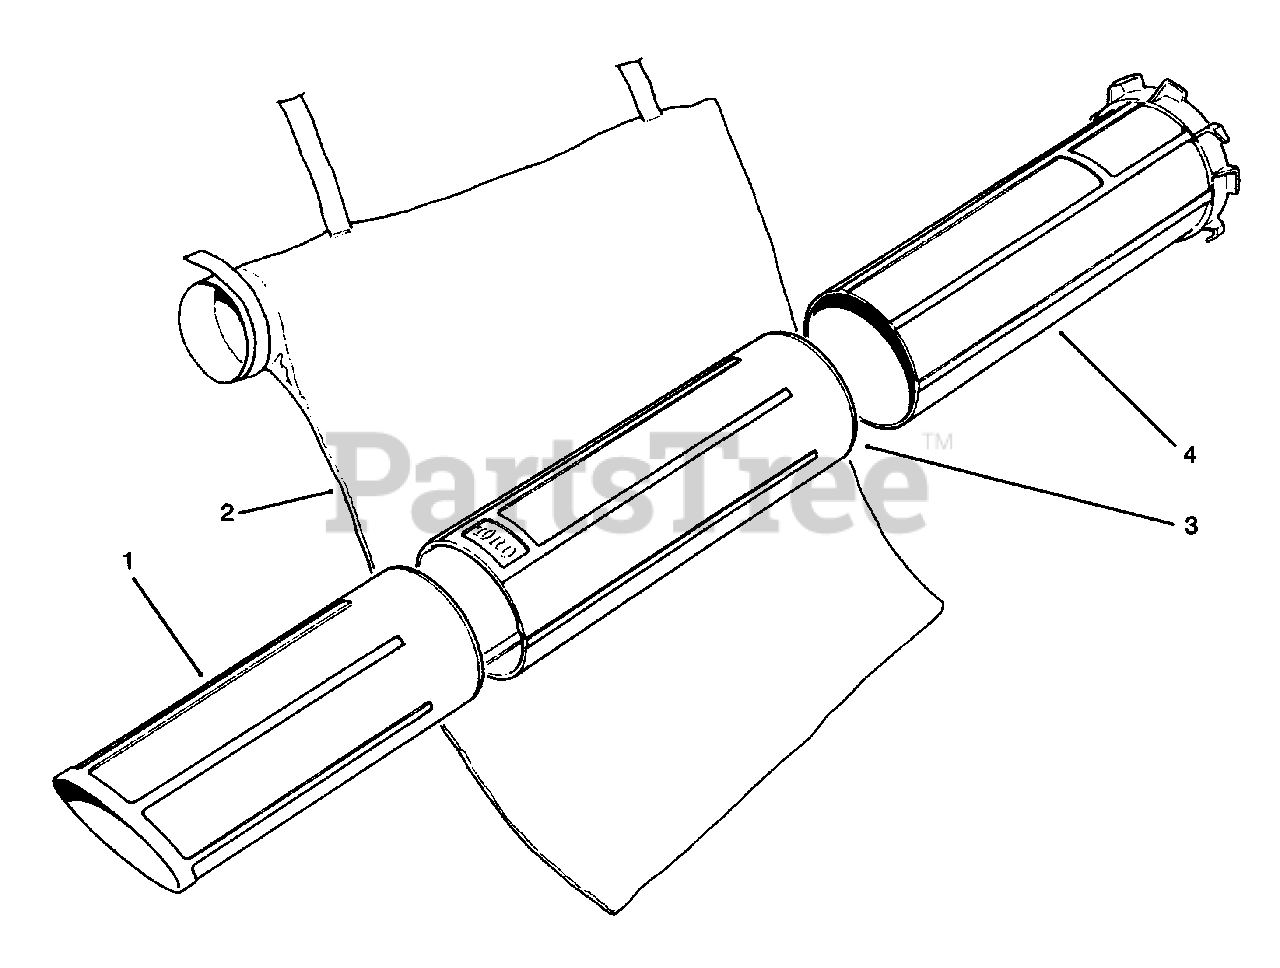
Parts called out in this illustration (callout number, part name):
1	Tube-Vacuum, Lower
2	Bag-Vacuum
3	Tube-Vacuum, Middle
4	Tube-Vacuum, Upper
